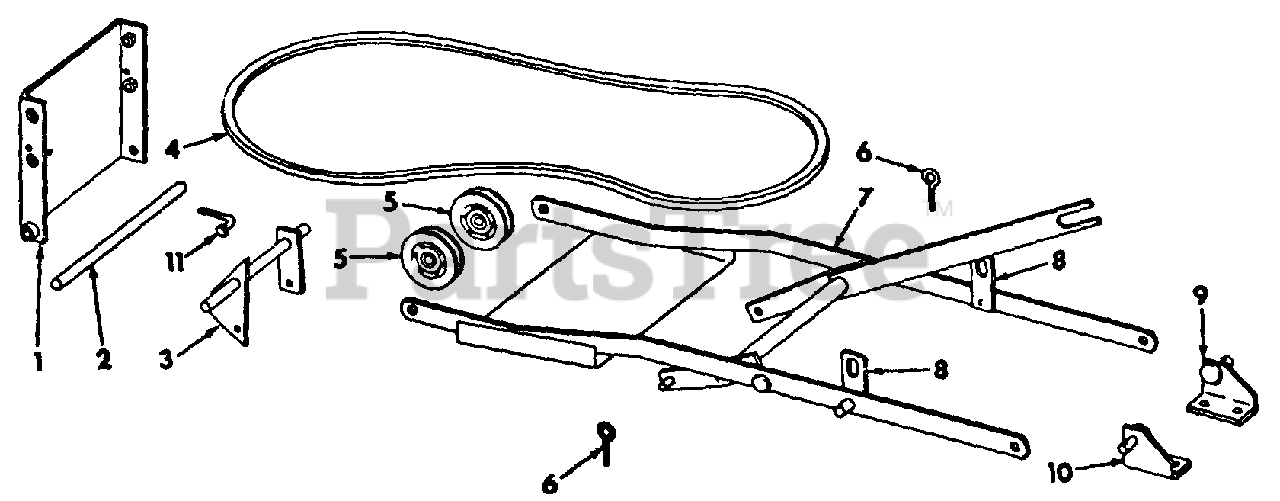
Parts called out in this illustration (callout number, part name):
1	SUPPORT ASSY, FRONT
2	PIN, FRONT MOUNTING
3	SUPPORT ASSY, IDLER
5	PULLEY, DRIVE BELT IDLER
7	FRAME ASSY, LIFT
8	LINK ASSY, LIFT
9	BRACKET ASSY, REAR HANGER RH
10	BRACKET ASSY, REAR HANGER LH
19417-R1	BOLT, 3/8-16 x 1 C-Z SQ-NK CRG
